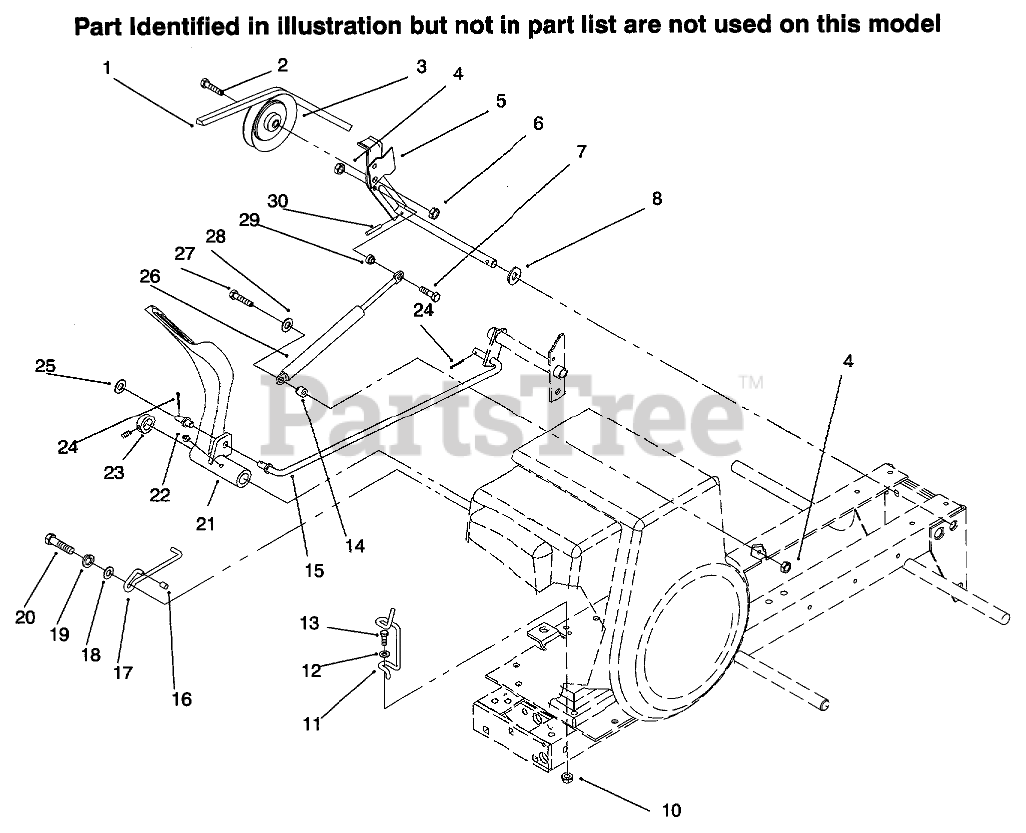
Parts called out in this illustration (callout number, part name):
1	BELT - V
2	BOLT-SPECIAL HEX
3	PULLEY-IDLER
4	NUT-LOCK, NI
5	Arm-Clutch Idler
6	NUT-HEX
7	Capscrew
8	SHIM-WASHER
10	NUT-LOCK, NI
11	GUIDE-BELT BOTTOM
12	WASHER-FLAT
13	SCREW-HH
14	SPACER-SHOULDER-.400
15	ROD-BRAKE
21	Pedal-Brake
22	FITTING-GREASE
23	COLLAR
24	PIN-COTTER
25	WASHER-NYLON
26	ASS'Y-GAS SPRING
27	SCREW-HH
28	WASHER-FLAT
29	SPACER-SHOULDER-.200
30	PIN-SPIROL
